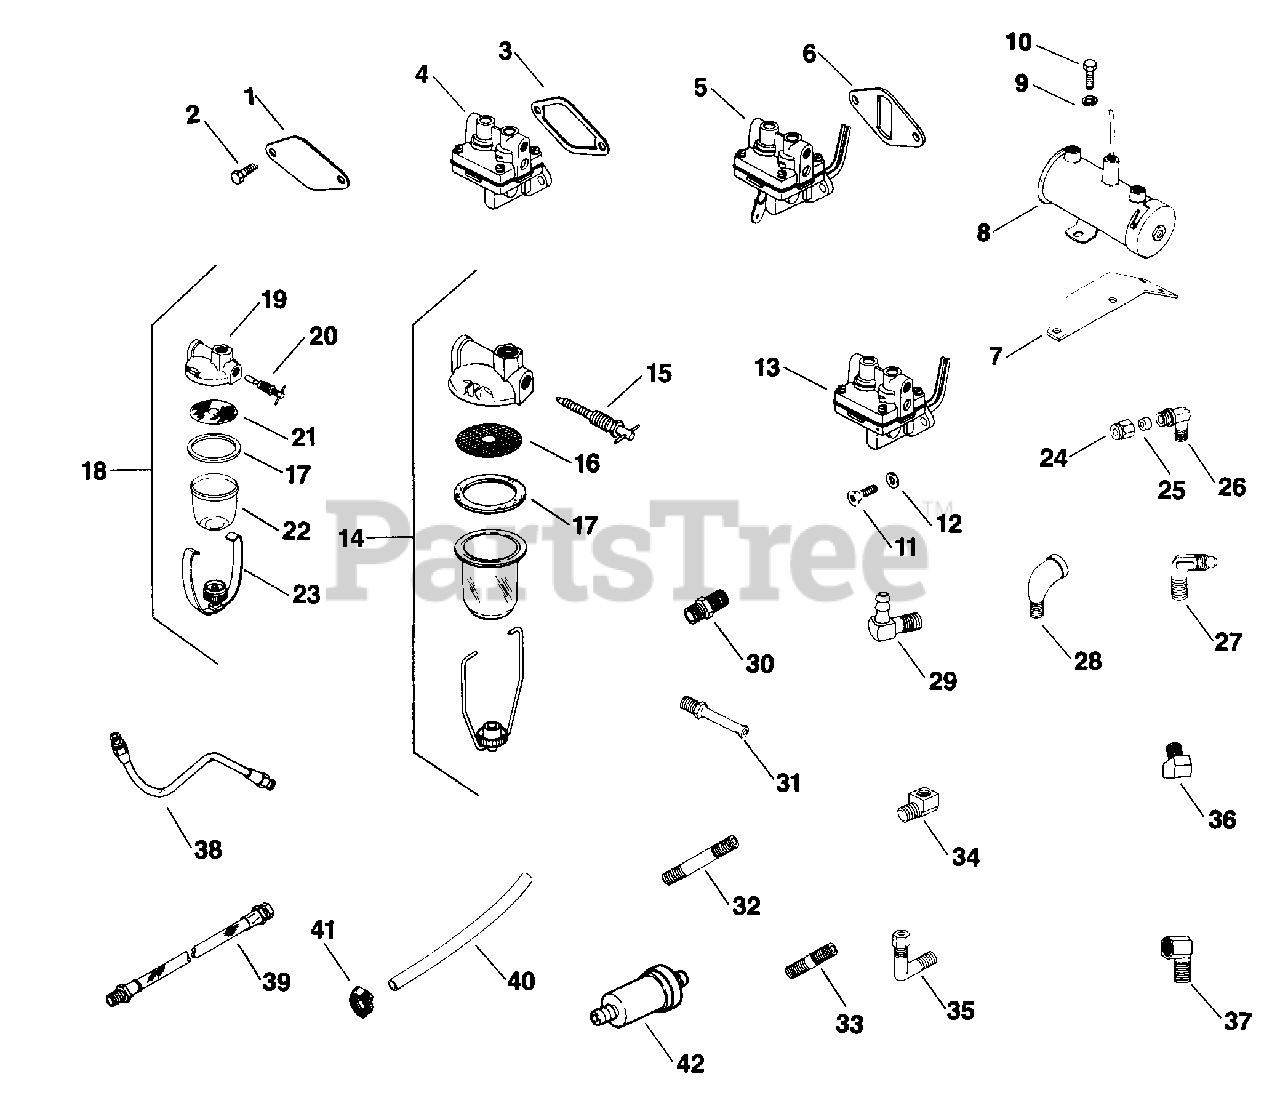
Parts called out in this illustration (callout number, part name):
5	FUEL PUMP, USE 41 559 05-S
6	GASKET - USE 25 041 09
18	KIT - USE 25 755 22
23	BAIL - DISCONTINUED
28	ELBOW - USE 25 054 10
33	PIPE - DISCONTINUED
41	CLAMP, HOSE 1/2" USE 25 237 14-S
